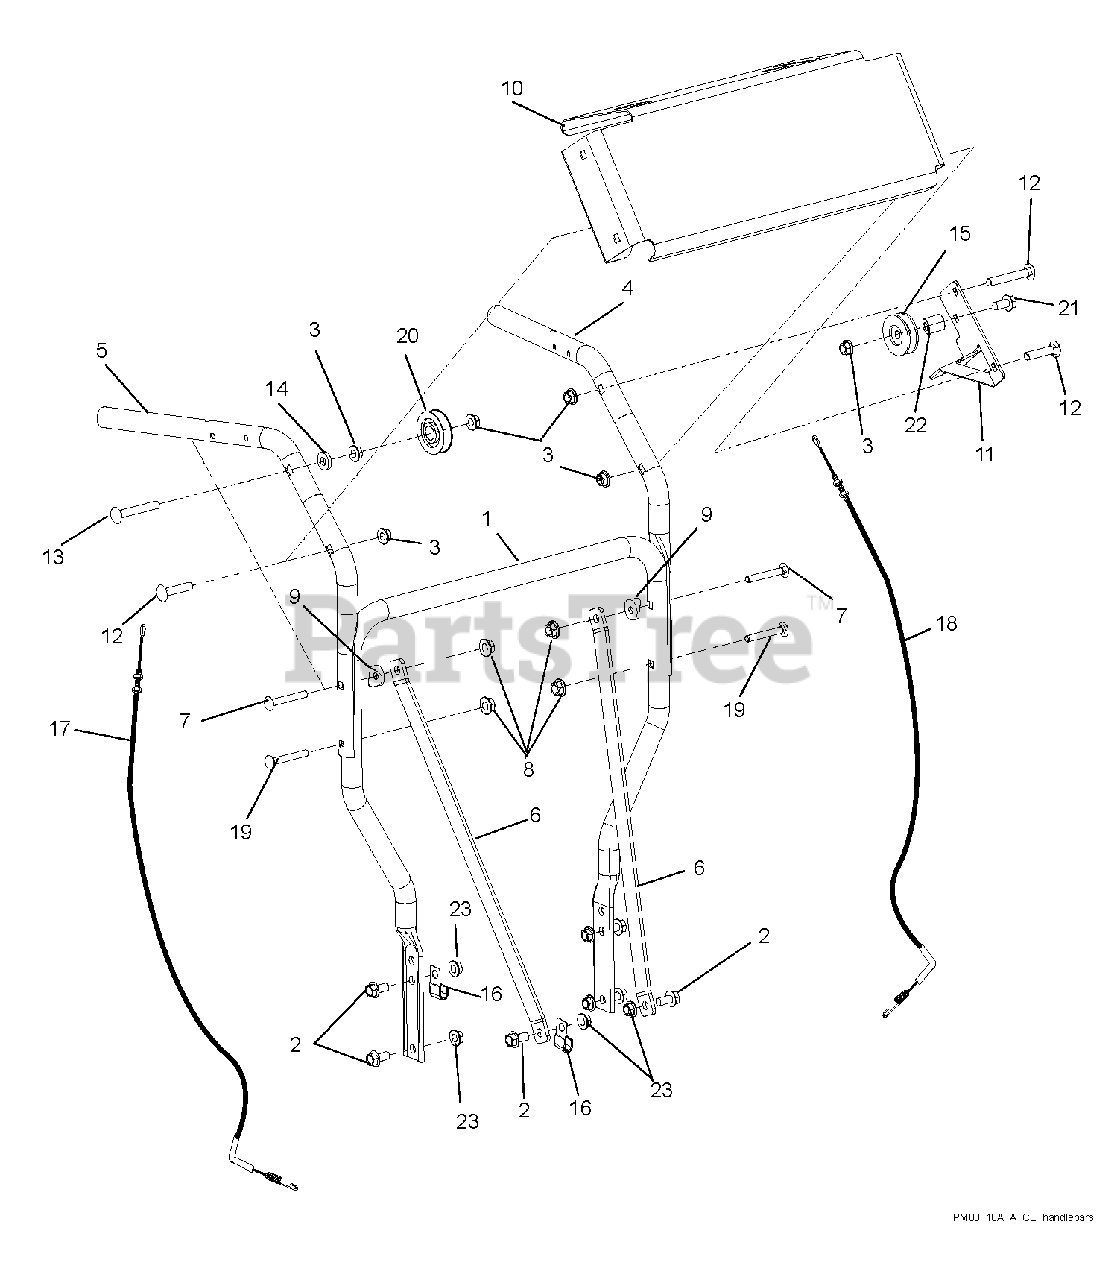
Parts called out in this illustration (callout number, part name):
1	Handlebar, Lower
2	Bolt, Screw Hex Flanged Whiz Lock Head .38-16 x .75
3	Nut, Locking Top Flange .38-16
4	Handlebar, Upper Left Hand
5	Handlebar, Upper Right Hand
6	Bracket, Handlebar Brace
7	Bolt, Round Head Square Neck .31-18 x 2.25
8	Nut, Nyloc Flange .31-18
9	Spacer, Handlebar
10	Dash, WAW
11	Mount, PTO Cable
12	Bolt, Round Head Square Neck .38-16 x 1.75
13	Bolt, Round Head Square Neck .38-16 x 2.50
14	Washer, Flat Steel .406 x 1.0 x .18
15	Idle, 3L Front Side .38 x 1.875
17	Cable, P-Brake
18	Cable, PTO
19	Bolt, Round Head Square Neck .312-18 x 1.75
20	Pulley, Cable
21	Bolt, Hex .38-16 x 2.50
22	Spacer, .437 x 1.00 x 1.23
23	Nut, Locking Center Flange .38-16
